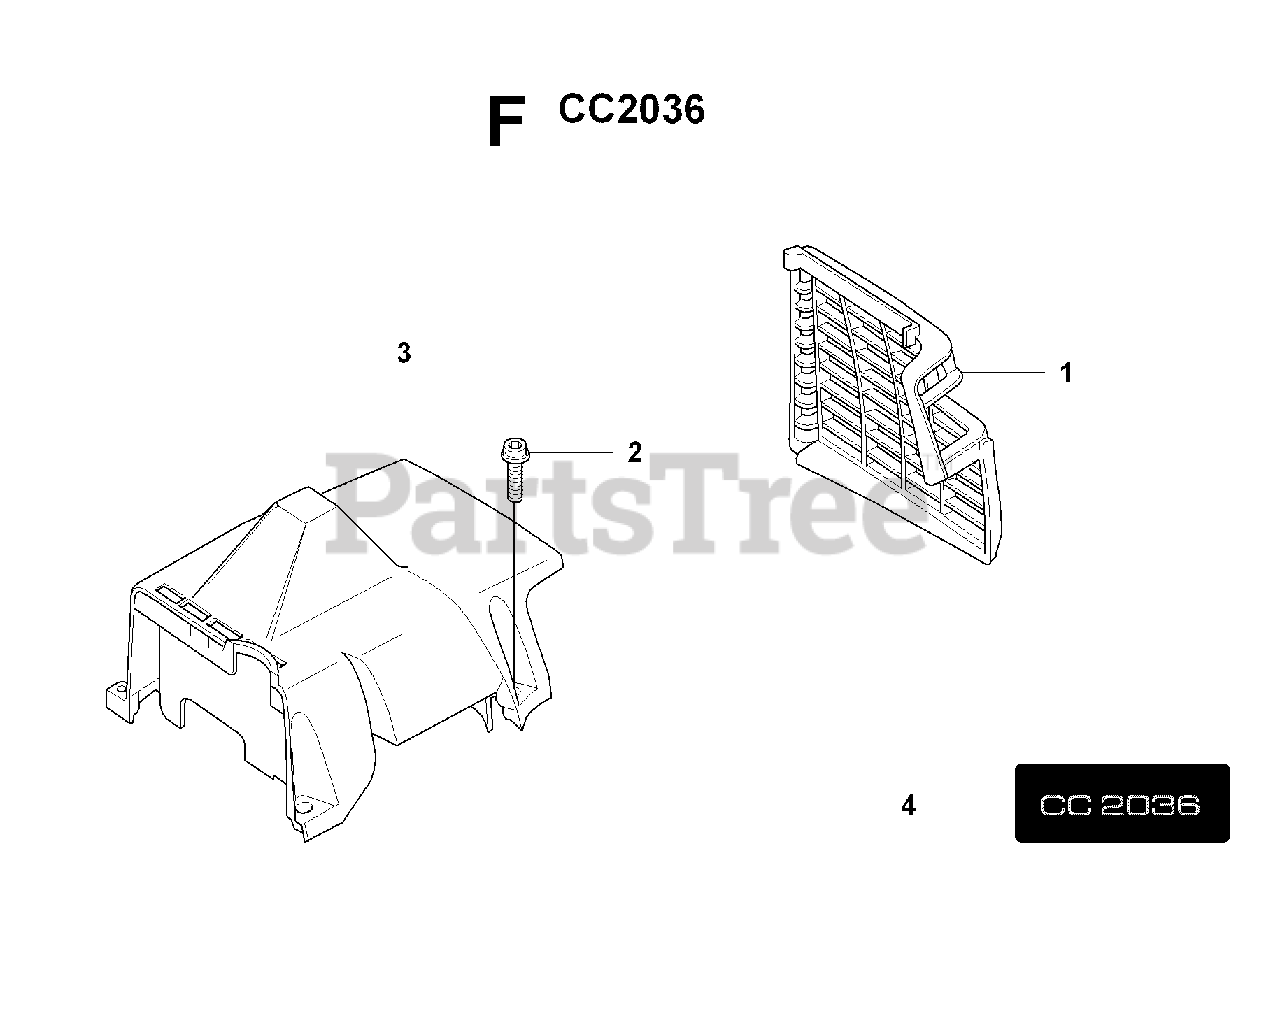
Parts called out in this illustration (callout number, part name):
1	PROTECTOR
2	SCREW
3	CYLINDER COVER
